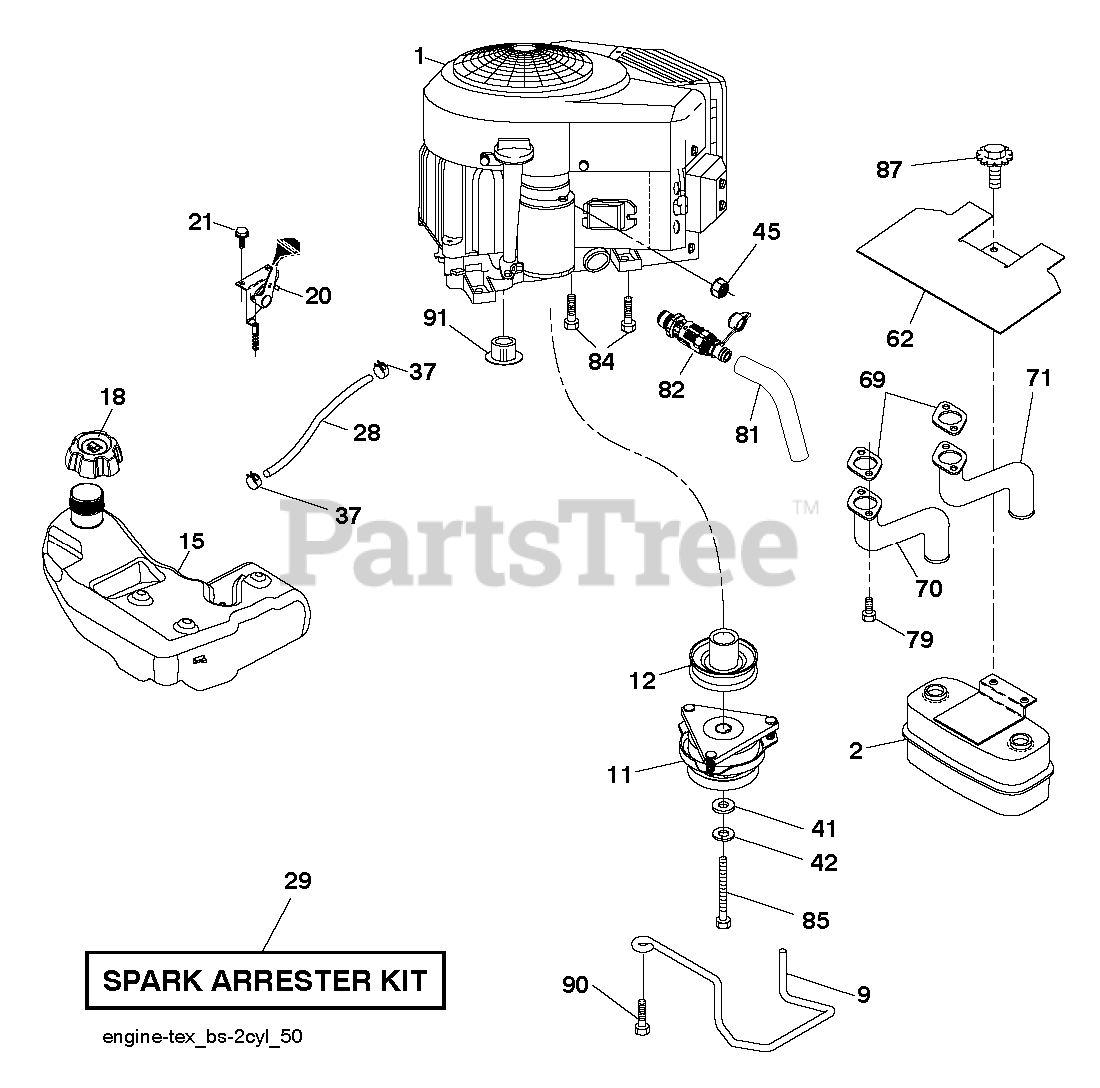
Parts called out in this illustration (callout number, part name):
2	MUFFLER.TWIN.CYL.LOW.TONE
9	KEEPER.BELT.ENGINE.4.2
11	CLUTCH.ELECTRIC.LT.48"*
12	PULLEY.ENGINE.TUFFTORQ
15	RP_TANK.ASSY.3.GAL.EPA
18	CAP.ASM.FL.RITCH.3"E10.SYM.498
20	CONTROL.TH/CK.COBRA.B&S.TWN.BK
21	SCREW.#10 X 0.750.BOS
28	LINE.FUEL.64"REAR.EMIS
29	Kit Spark Arrestor 1 25
37	HOSE CLAMP
42	LOCKWASHER
45	NUT
62	RP SHIELD HEAT MUFFLER
69	GASKET.MUFFLER
70	RP.EXHAUST.TUBE.LH.BS/TWIN
71	EXHAUST.TUBE.RH.BS/TWIN
79	SCREW.SOCKET.HEAD.5/16-18
81	TUBE, DRAIN OIL ASM.
82	VALUE.OIL.DRAIN
84	SCREW.3/8-16
85	BOLT HEX 7/16-20X4-1/4"
87	BOLT.5/16-18UNCX3/4 W/SEMS.BLK
90	SCREW 3/8-16X1
91	BUSHING.1.375OD
